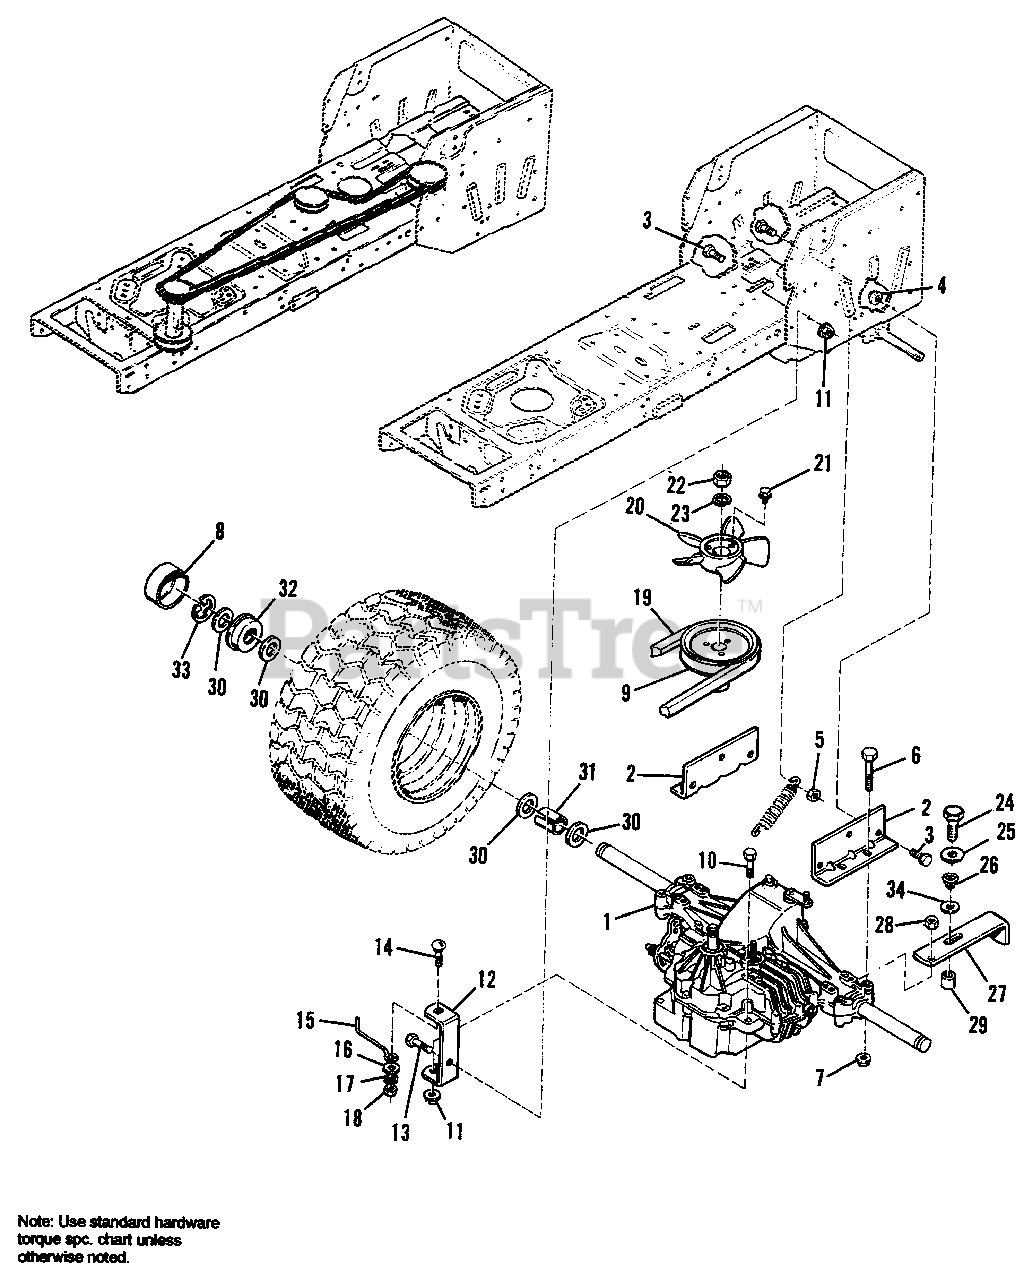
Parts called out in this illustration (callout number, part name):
1	TRANSMISSION, Hydro
2	SUPPORT, Trarsmission, Rear
3	CAPSCREW, Hex Hd., 3/8-16 x 1
4	LOCKNUT, Hex, Flange, 3/8-16
5	LOCKNUT, Hex, 3/8-16
6	CAPSCREW, Hex Hd., 5/16-18 x 2-1/2
7	NUT, Hex, Flange Lock, 5/8-18
9	PULLEY ASSY.
10	CAPSCREW, Hex Hd., 5/16-18 x 1-1/4
11	NUT, Hex, Whiz Lock, 5/16-18
12	STRAP, Torque
13	CAPSCREW, Hex Hd., 5/16-18 x 3/4
14	CARRIAGE BOLT, 5/16-18 x 1
16	WASHER, 11/32 x 1 x 3/16
17	LOCKWASHER, 5/16
18	NUT, Hex, 5/16-18
21	SCREW, Taptite, 1/4-20 x 1-1/64
22	NUT, Hex, Jam, 1/2-20
23	LOCKWASHER, 1/2
24	SCREW, Taptite, Hex Hd., 10-24 x 1-1/4
25	WASHER, Plain, 1/4 x 1-11/32 x 1/16
26	SPRING, Conical
27	LEVER, Tow Valve
28	NUT, Hex, Full Lock, 1/4-20
30	WASHER, Plain, 3/4 x 1-5/8 x 1/8
32	RETAINER, Hub Cap
34	WASHER, Plain
